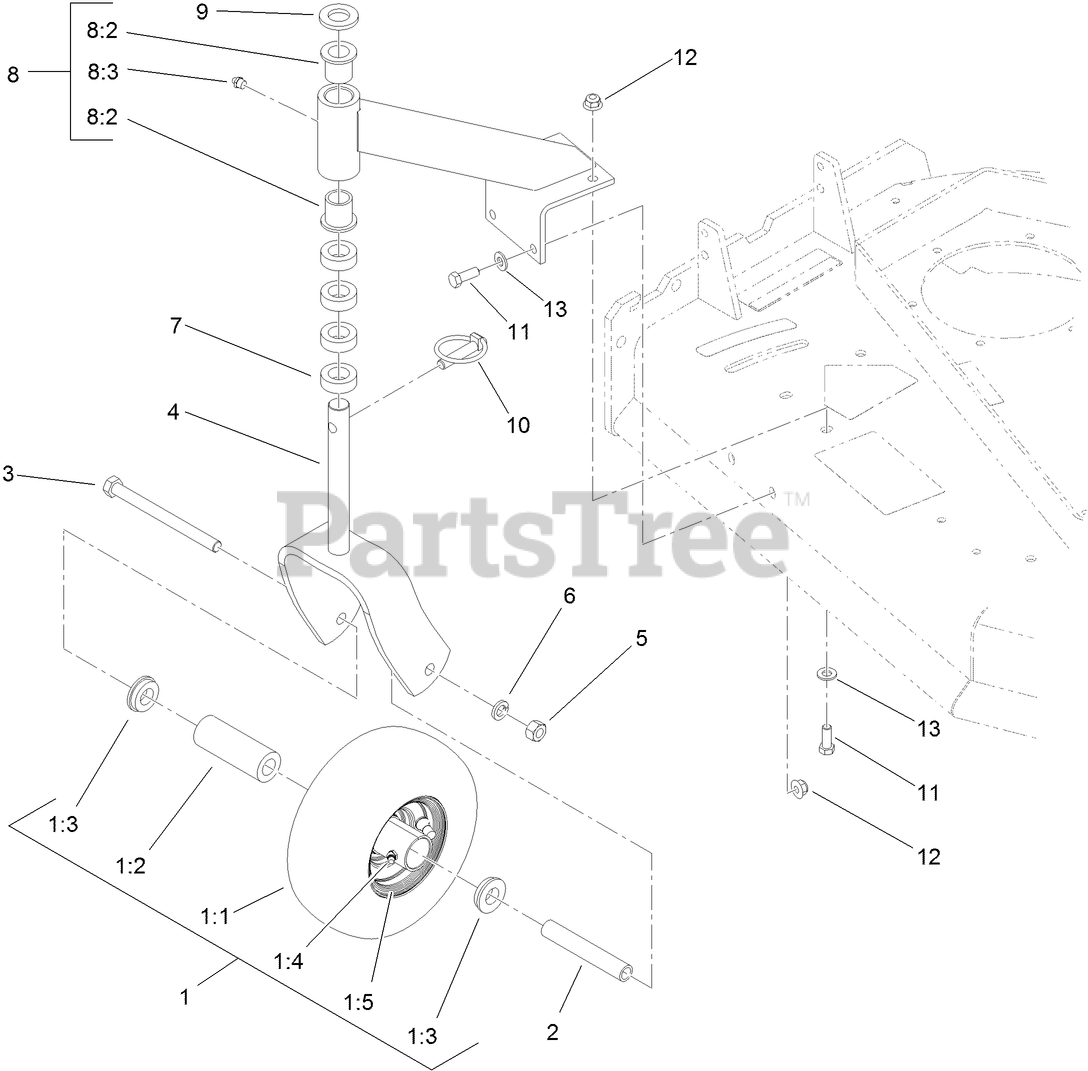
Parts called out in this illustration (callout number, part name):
1	WHEEL AND TIRE ASM
1:1	TIRE
1:2	BEARING
1:3	BUSHING
1:4	FITTING-GREASE
1:5	WHEEL
2	SPACER
3	SCREW-HH
4	FORK
5	NUT-HH
6	WASHER-LOCK
7	SPACER-CASTER
8	SUPPORT ASM
8:2	BEARING-FLANGED
8:3	FITTING-GREASE
9	WASHER-FLAT
11	SCREW-HH
12	NUT-HF, NI
13	WASHER-FLAT
